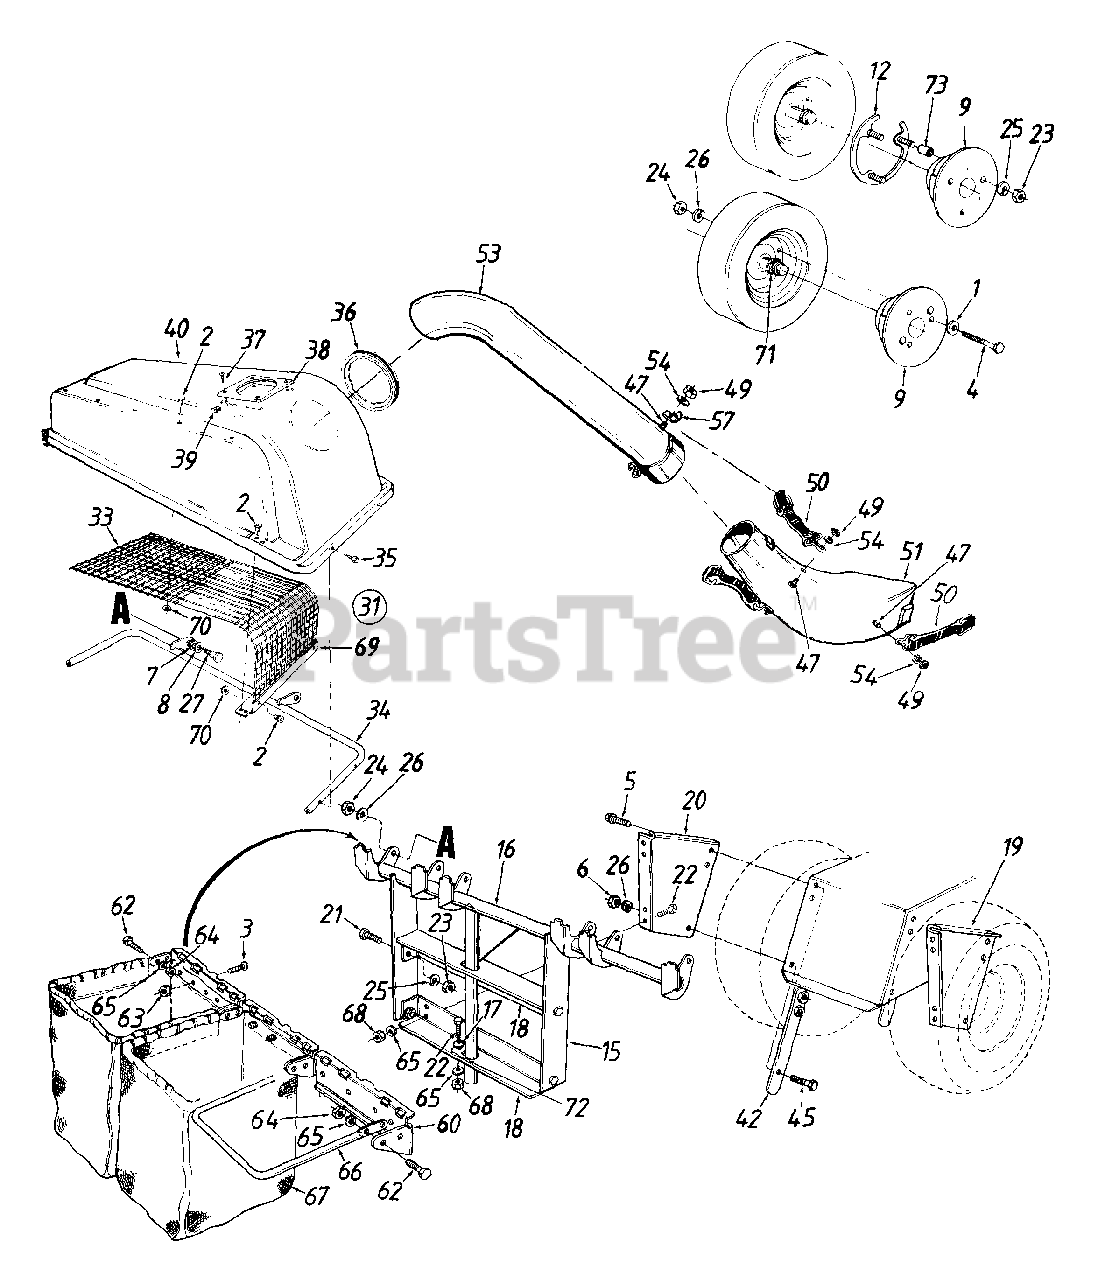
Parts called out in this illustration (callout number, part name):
1	Fl-Wash..385" I.D.
2	Pop Rivet
3	Truss Mach. Scr. #10-24 x .38" Lg.
4	Hex Bolt 3/8-16 x 4.5" Lg.
5	Hex Wash. Hd. Tap Scr. 5/16-18 x .62"
6	Hex Nut 3/8-24 Thd.
7	Bell-Wash..515" I.D.
8	Fl-Wash..510" I.D.
15	Catcher Support Tube Mtg. Brkt.
18	Catcher Latch and Support Brkt.
22	Hex Bolt 1/4-20 x .62" Lg.- Grade 5
23	Hex Nut 5/16-18 Thd.
24	Hex Nut 3/8-16 Thd.
25	L-Wash. 5/16" I.D.
26	L-Wash. 3/8" I.D.
27	Shld. Bolt 3/8-16 x .500" Dia.
31	Grass Catcher Cover Ass'y. Comp.
33	Screen
36	Tube Seal
37	Truss Mach B-Tap Scr. #10 x .5" Lg.
38	Plastic Plate
39	Speed Nut
40	Grass Catcher Cover
47	Hex Bolt 1/4-20 x .50" Lg.
49	Hex Ins. L-Nut 1/4-20 Thd.
50	Retainer Strap Ass'y.
51	Discharge Chute
53	Catcher Elbow Tube
54	L-Wash..270" I.D. x .57" O.D.
57	Retainer Hook Brkt.
62	Hex Bolt 1/4-28 x .75" Lg.
63	Hex Sems Nut #10-24 Thd.
64	Hex Nut 1/4-28 Thd.
65	L-Wash. 1/4" I.D.
66	Catcher Bag Frame
67	Grass Catcher Bag
68	Hex Nut 1/4-20 Thd.
71	Foam Strip 1-1/8" x 1-1/2" x 3/8"
73	Spacer
